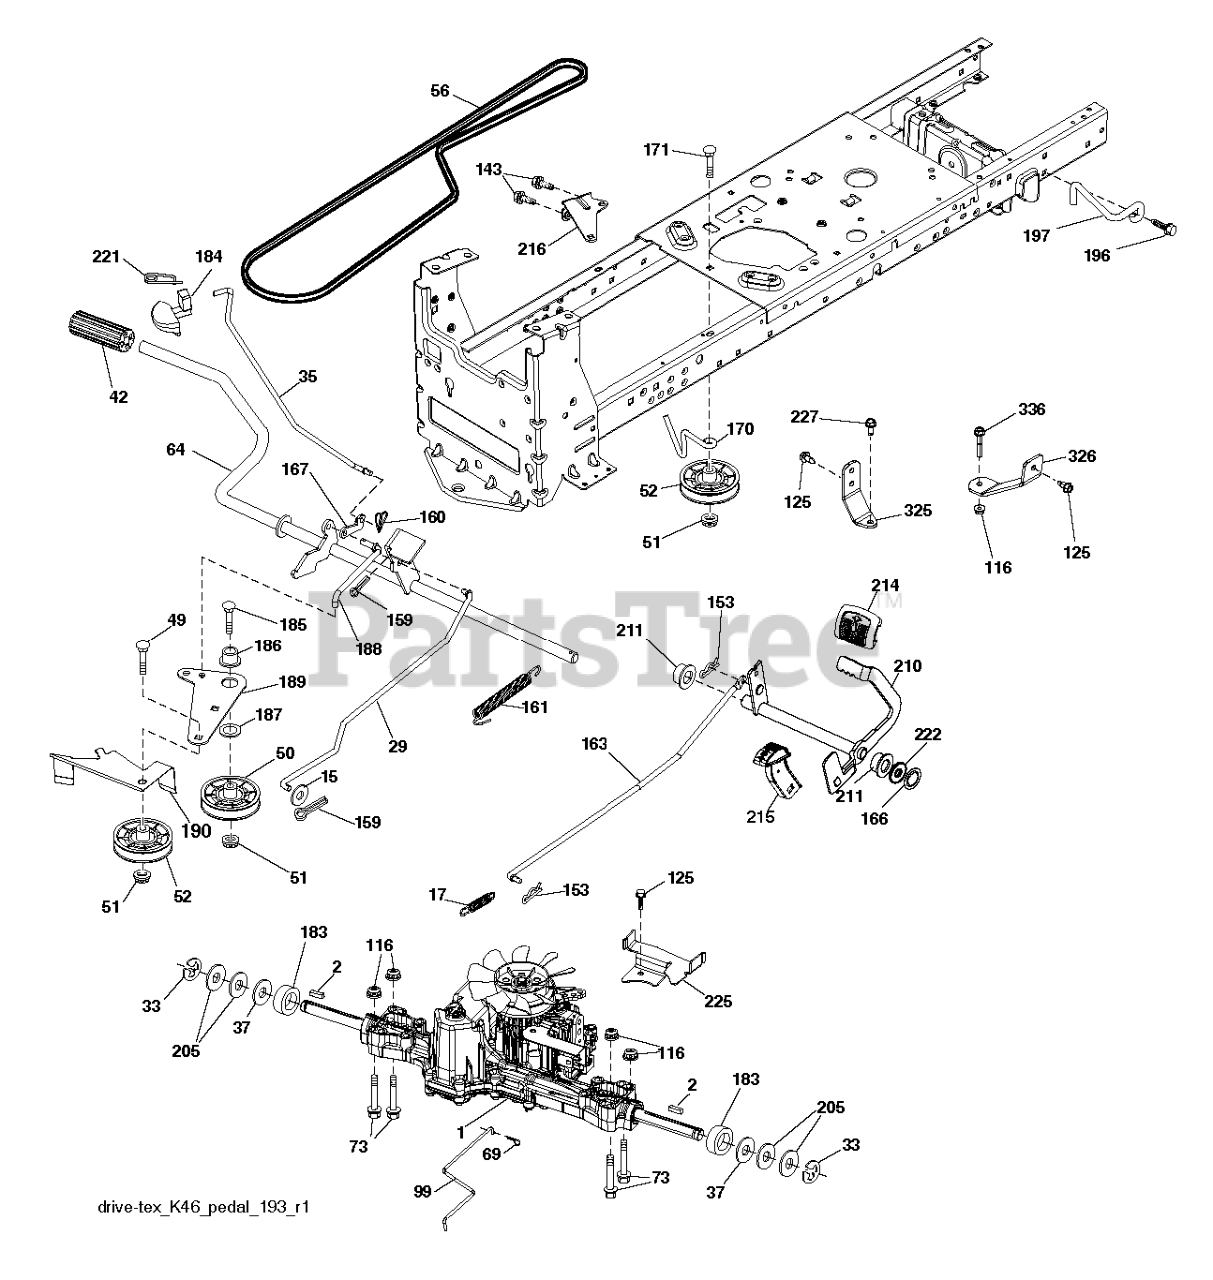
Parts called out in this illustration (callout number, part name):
2	SQUARE KEY
15	WASHER
17	SPRING.BRAKE.K46.GREEN
29	ROD.BRAKE.K46
35	ROD.CNTRL.PARK.PREDATOR.LT.TEX
37	WASHER.HARDENED
42	PEDAL COVER T
50	IDLER.FLAT.910.OFFSET
51	NUT LOCK FLG 3/8-16 UNC
52	IDLER.V-GROOVE.910.OFFSET
56	V-BELT.MOWER.92.40.42/K46
64	SHAFT.ASM.PEDAL.BRK.CNTR
69	HAIRPIN.SOFT.ZINC.059X1.125
99	ROD.SPRING.BYPASS.K46.LT.Z
116	NUT LOCK HEX FLANGE 5/16-18
125	SCREW
143	SCR 5/16-18 X 1/2 SELFTAP ZN
153	RETAINER M
159	COTTER PIN
160	RETAINER CLIP
161	SPRING, RETURN LT
163	ROD.CONTROL.K57R.K46
166	NUT.PUSH.625
167	LATCH.BRAKE.SPRING
170	KEEPER.V-IDLER.CENTER.
183	SPACER AXLE
184	HANDLE.PARKNG BRK.PRED.LT.428
186	SPACER.RETAINER
187	WASHER 12/32X2X10GA
188	RP.LINK.CLUTCH.GROUND.DRIVE
189	BELLCRANK.GROUND.DRIVE.TEX.
190	KEEPER.BELLCRANK.DRIVE
196	SCREW 3/8-16X1
197	CLUTCH.ANTIROTATION.WIREFORM.
210	ROCKER.ASM.PEDAL.CONTR
211	BEARING.NYLON
214	PEDAL.FORWARD.PAD.TEX
215	PEDAL.REVERSE.TEX.GT.4
216	BRACKET.PULLEY.IDLER.W/TEX
221	RETAINER.SPRING.CLIP.H
222	WASHER 21/32 X 1-1/4 X 10 GA.
225	KEEPER.BELT.TRANSAXLE.K46
227	SCREW.THDROL.5/16-18X3/4.TTY
325	BRACKET.TRQ.STP.46.20".TIRE.LH
326	BRCKT.PNT.TRQ.STP.46.20TIRE.RH
336	BOLT.5/16-18X1-3/4.FLANGED.HEX
